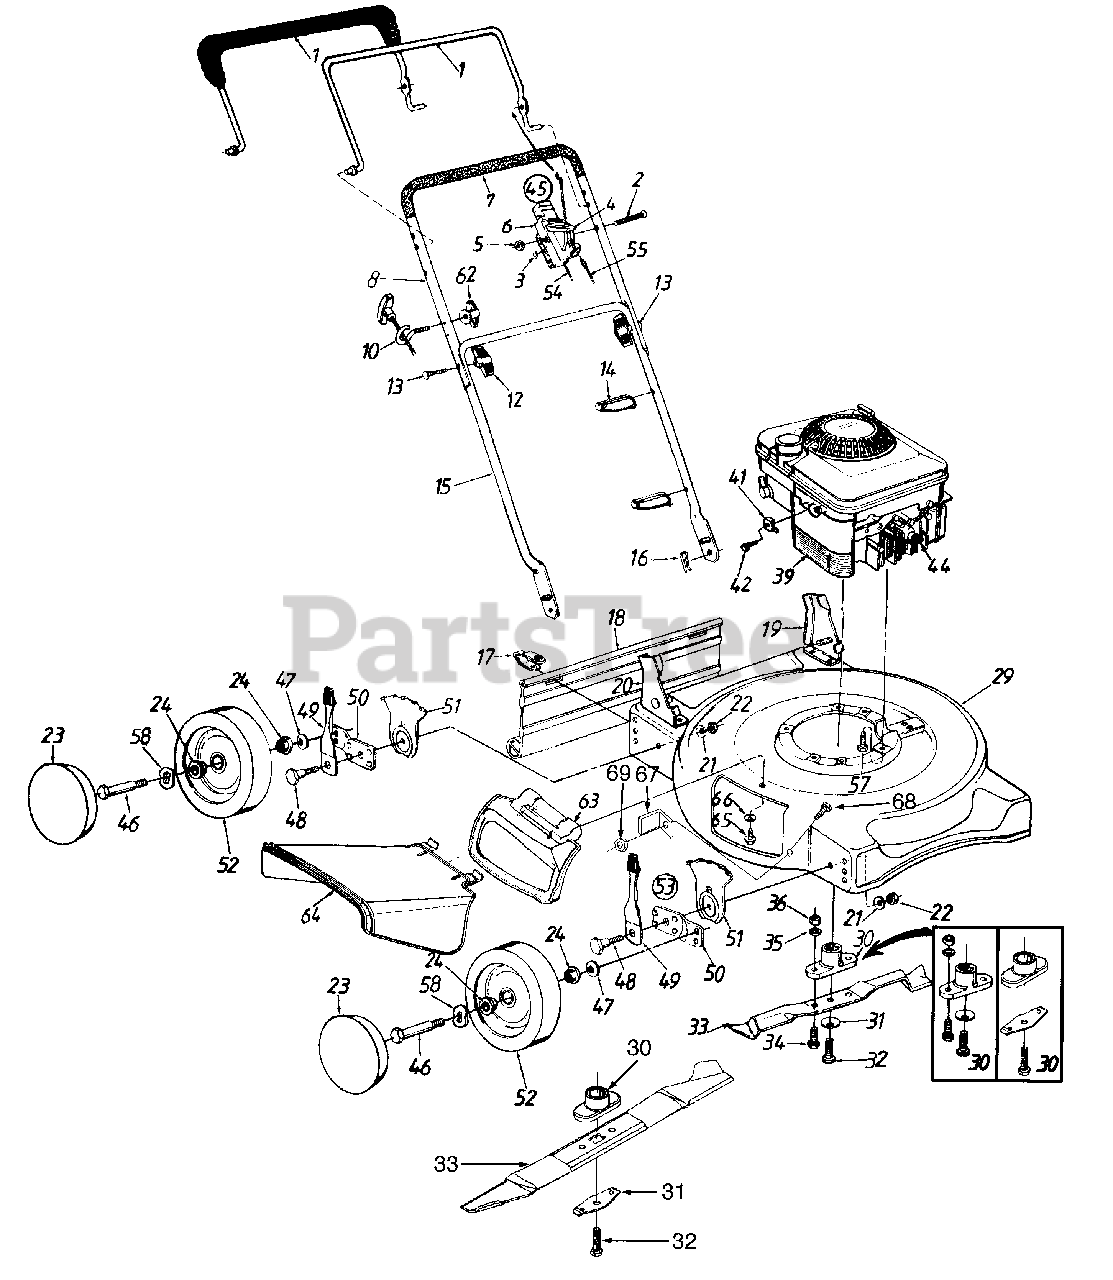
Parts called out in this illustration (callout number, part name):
1	Control Handle Ass'y. (Dlxe)
2	Oval C-Sunk Scr.
3	Spr. Wash. .66" I.D.
4	Throttle Lever
5	Hex L-Nut 1/4-20 Thd.
6	Throttle Body
7	Grip
12	Hand Knob
13	Cur. Hd. Bolt 5/16 - 18 x 2" Lg.
14	Cable Tie
16	Hairpin Cotter
17	Hinge Clip
18	Rear Flap
21	Bell - Wash. .39" I.D. x 1.38"
22	Hex Nut 3/8-16 Thd.
23	Hub Cap
24	Bearing
29	20" Deck Ass'y.
30	Blade Adapter Kit
31	Bell-Wash. .39" I.D
32	Hex Bolt 3/8-24 x 1.5" Lg.
33	20" Mulching Blade
34	Hex Bolt 3/8-24 x 1" Lg.
35	L-Wash. 3/8" I.D.
36	Hex Nut 3/8-24 Thd.
39	Engine
41	Cable Clamp
42	Hex Self-Tp Scr. #10-32 x .62"
44	Spark Plug Boot
45	Throttle Box Comp.
46	Axle Bolt
47	Bell-Wash. .400" I.D. x .88"
48	Shld. Bolt .50" Dia. x .357"
49	Spring Lever Ass'y. w/Knob
51	Height Adj. Plate
52	Wheel Ass'y. Comp.
53	Height Adj. Ass'y. Comp.- R.F. & L.R.
54	Throttle Cable - 51"
55	Control Cable - 39"
57	Hex L-Wsh. Scr. 3/8-16 x 1.0" L
58	Wave Washer .51" I.D.
62	Handle Knob 1/4-20 Thd.
63	Mulching Plug
64	Chute Deflector
65	Bell-Wash. 1/4" I.D.
66	Hex Wash. Hd. TT-Tap Scr. 1/4-20 x .5" Lg.
69	Scr. 1/4-20
